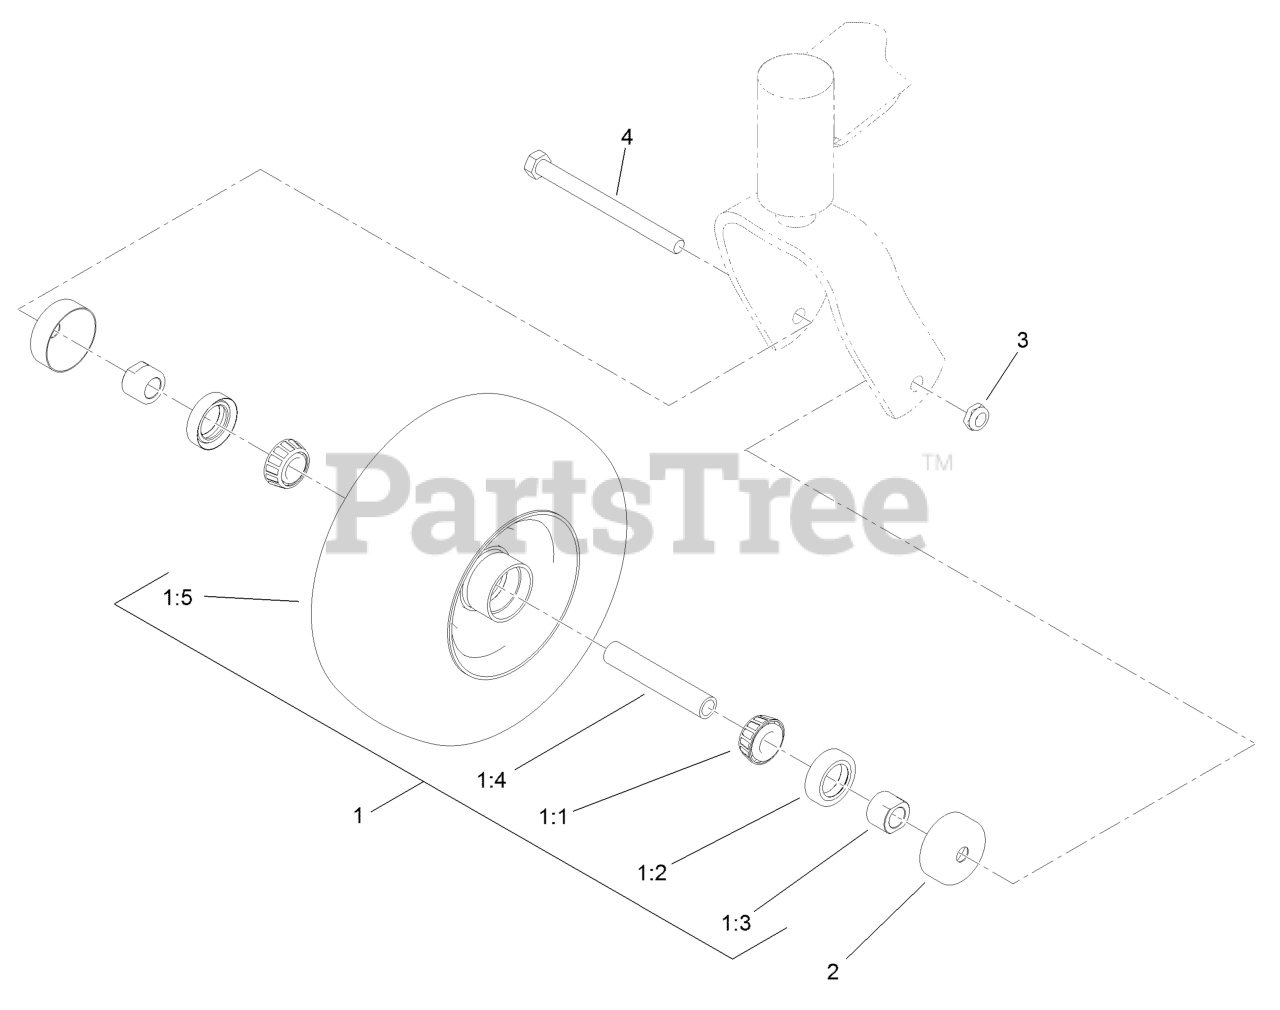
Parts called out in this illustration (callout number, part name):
1	Wheel And Bearing ASM
1:1	BEARING-CONE, TAPERED ROLLER
1:2	SEAL-CASTER
1:3	SPACER-NUT
1:4	CASTER AXLE ASM
1:5	WHEEL AND TIRE ASM
2	GUARD-SEAL
3	NUT-HEX
4	SCREW-HH
